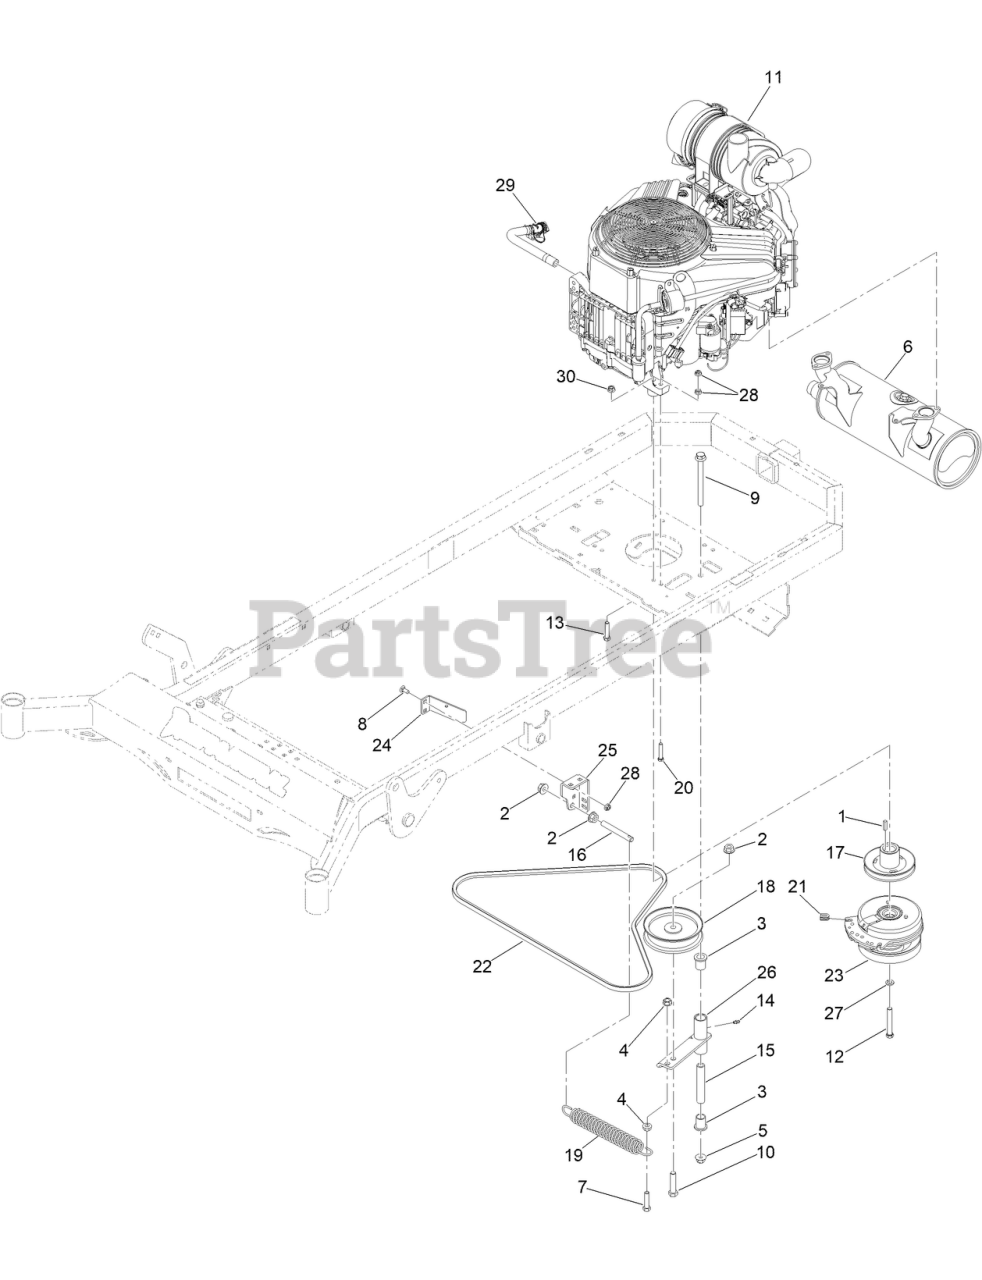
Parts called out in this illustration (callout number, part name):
2	NUT-HHF
3	3/4IN ID X15/16IN OD X 1-1/8IN FLNG BUSH
4	NUT-HF
5	NUT-LOCK
6	MUFF W/SPARK ARRESTER 6.00INOD1.5IN TP
7	SCREW-HH
8	BOLT-CARR
9	1/2-13 X 5-1/2 HEX FLANGE BOLT GR 8 ZY
10	SCREW-HH
11	VANGUARD 37EFI ENGN
12	7/16-20 X 3 HEX C/S GR 8 ZC YELLOW
13	SCREW-HH
14	1/4IN DRIVE TYPE GREASE FITTING YZ
15	MWR INNER IDLER SPACER
16	MWR PUMP IDLER SPRING TENSIONER
17	MWR HYDRAULIC PUMP DRIVE PULLEYA BELT
18	5-3/4IN IDLER PULLEY 7/16IN SPACER ASSY
19	MWR DECK SPRING
20	5/16-18 X 1-3/4 HEX C/S GR 5 ZINC YELLOW
21	MWR CLUTCH ROTATION STOP BRKT SLEEVE
22	MWR PUMP BELT RT A X 68.25IN EFF LNGTH
23	WARNER PTO CLUTCH
24	MWR CLUTCH ANTI ROTATION BRKT PAINTED
25	MWR PUMP IDLER TENSIONING BRKTPAINTED
26	MWR PUMP IDLER ASSY PAINTED
27	WASHER-LOCK
29	VANGUARD OIL DRAIN HOSE WITH CAP 11.5 L
30	3/8-16 HEX FLANGE NUT W/SERR ZINC YELLOW
